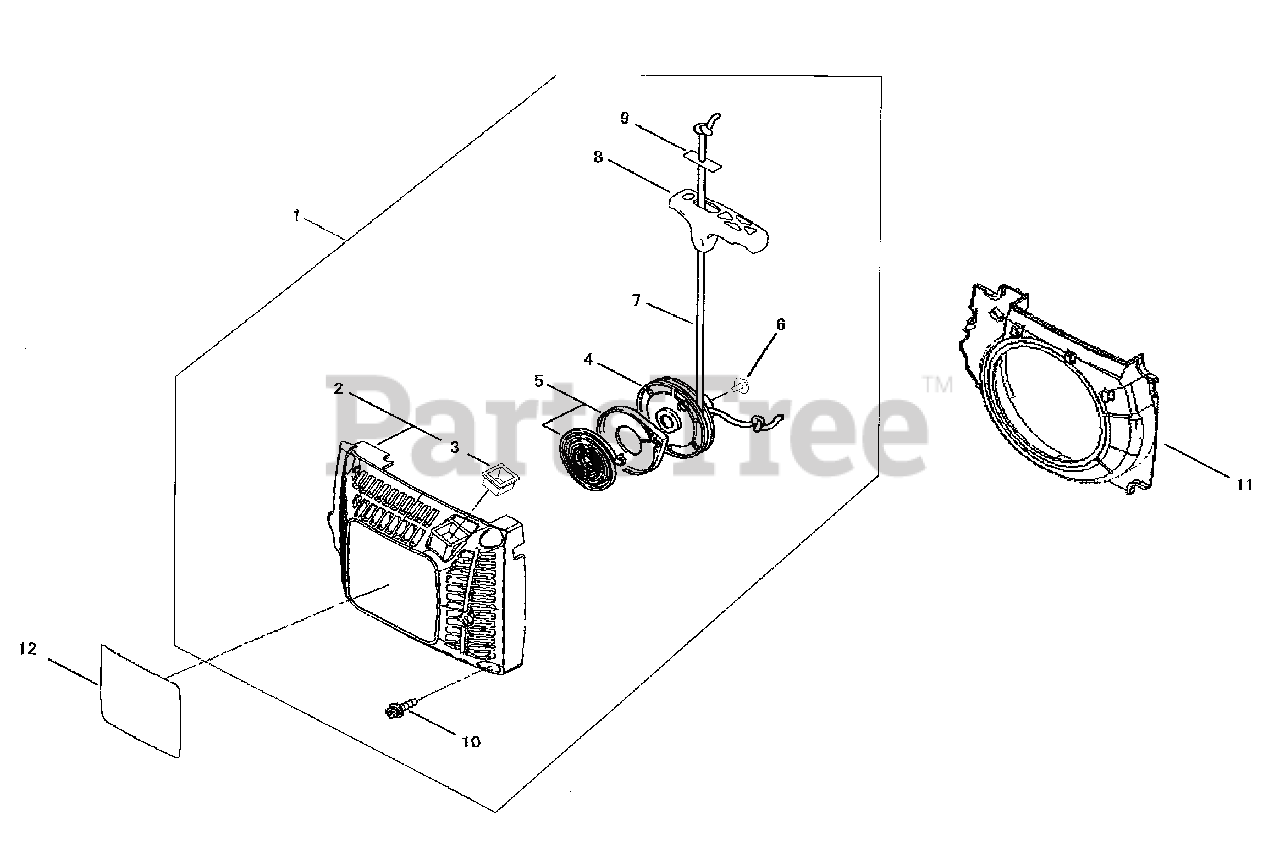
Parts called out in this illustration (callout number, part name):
1	STARTER ASSY
2	COVER
3	GUIDE, ROPE
4	REEL, ROPE
5	REWIND SPRING ASSY
6	SCREW -- TAPPING
7	ROPE
8	GRIP, STARTER
9	RETAINER, ROPE
10	SCREW - 4X16
11	DEFLECTOR, AIR
12	LABEL - MODEL 490
